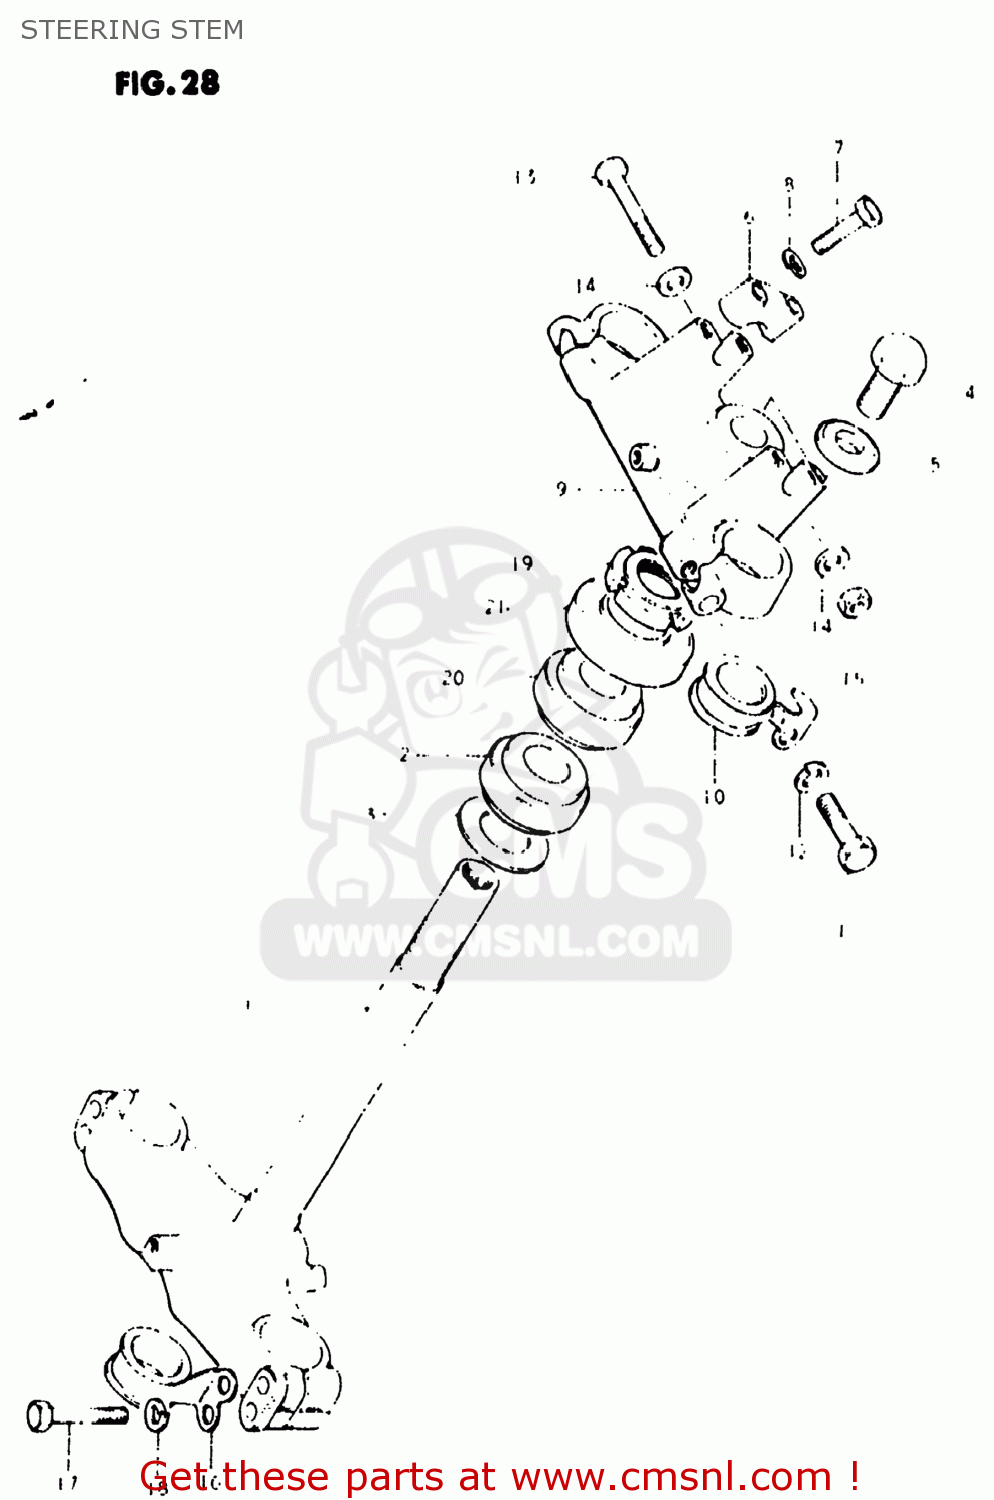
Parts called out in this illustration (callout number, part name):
1	STEM,STEERING
2	BEARING
3	WASHER,THRUST
4	BOLT
5	WASHER
6	HOLDER,HANDLEBAR
7	BOLT
8	LOCK WASHER
9	HEAD,STEERING STEM
10	GUIDE,CABLE
11	BOLT
12	LOCK WASHER
13	BOLT 8X50
14	WASHER
15	NUT
16	GUIDE,CABLE
17	BOLT 8X45
18	LOCK WASHER
19	NUT,STEERING STEM(25X44X10)
20	TAPER,ROLLER BEARING
21	DUST SEAL,STEERING,UPPER
